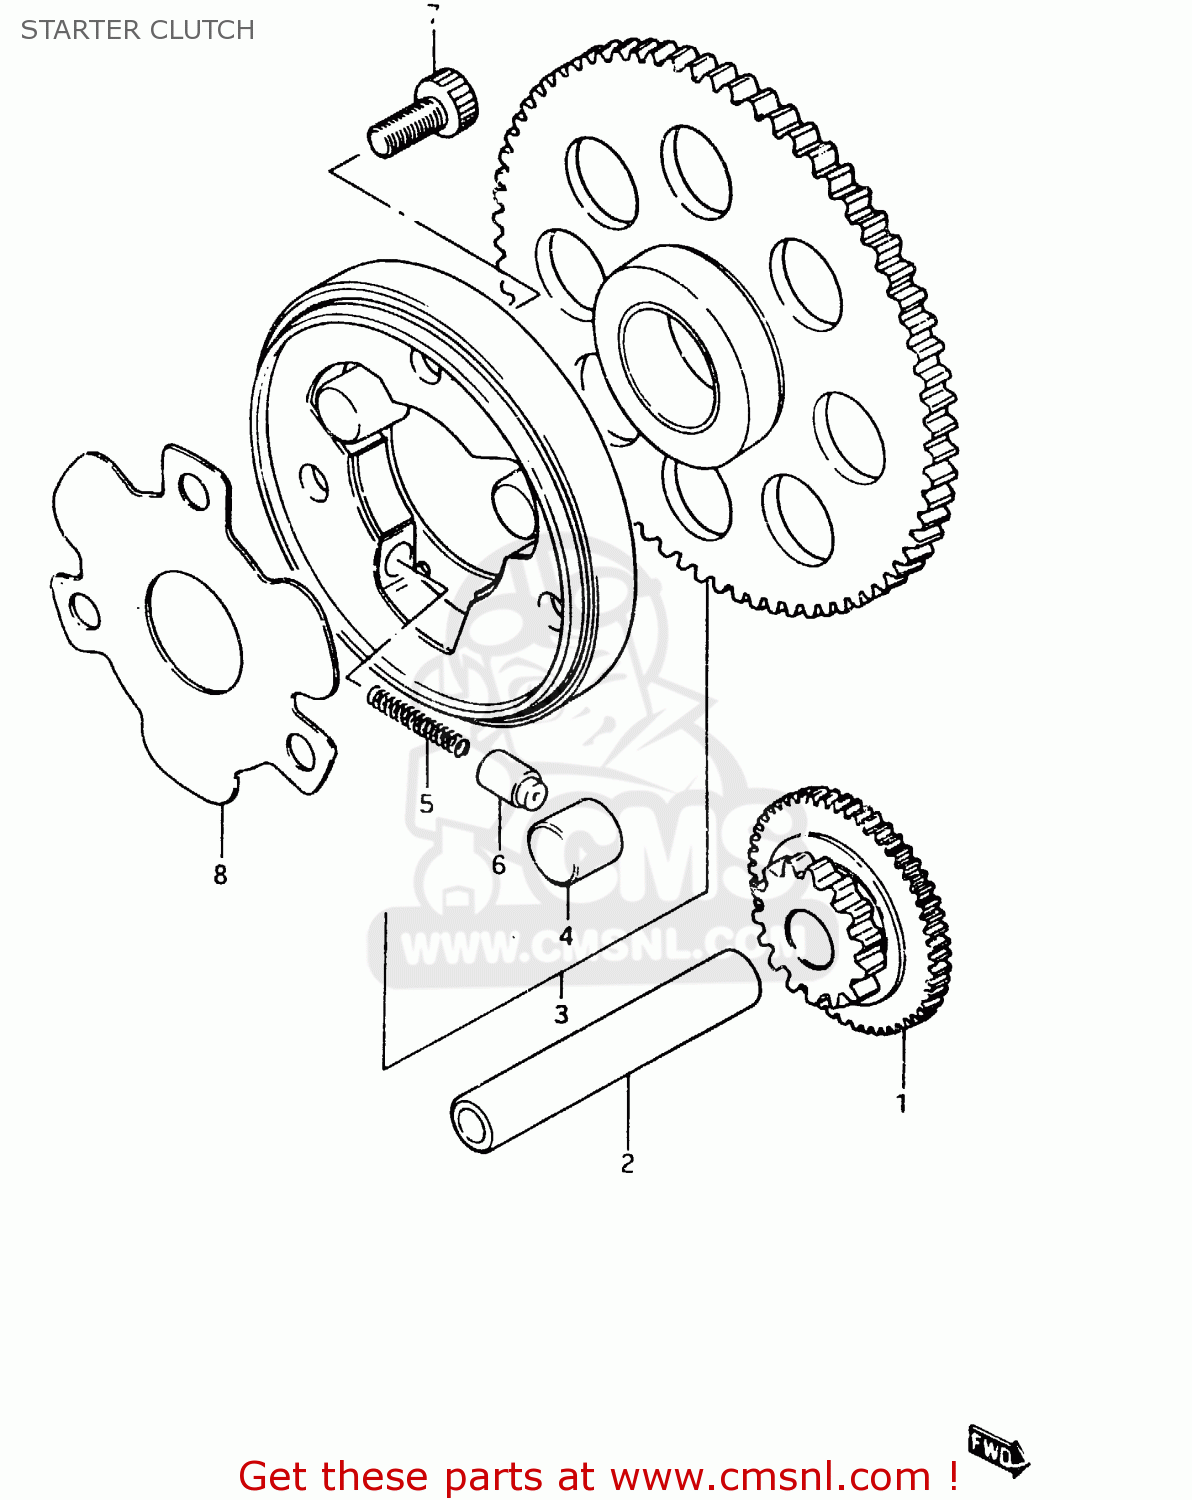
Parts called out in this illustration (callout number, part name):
1	GEAR,STARTER IDLE
2	PIN(7.4X13X56)
3	CLUTCH SET,STARTER
4	PIN(14X13)
5	SPRING
6	PIECE,PUSH
7	BOLT
8	SHIM,STARTER CLUTCH HUB
